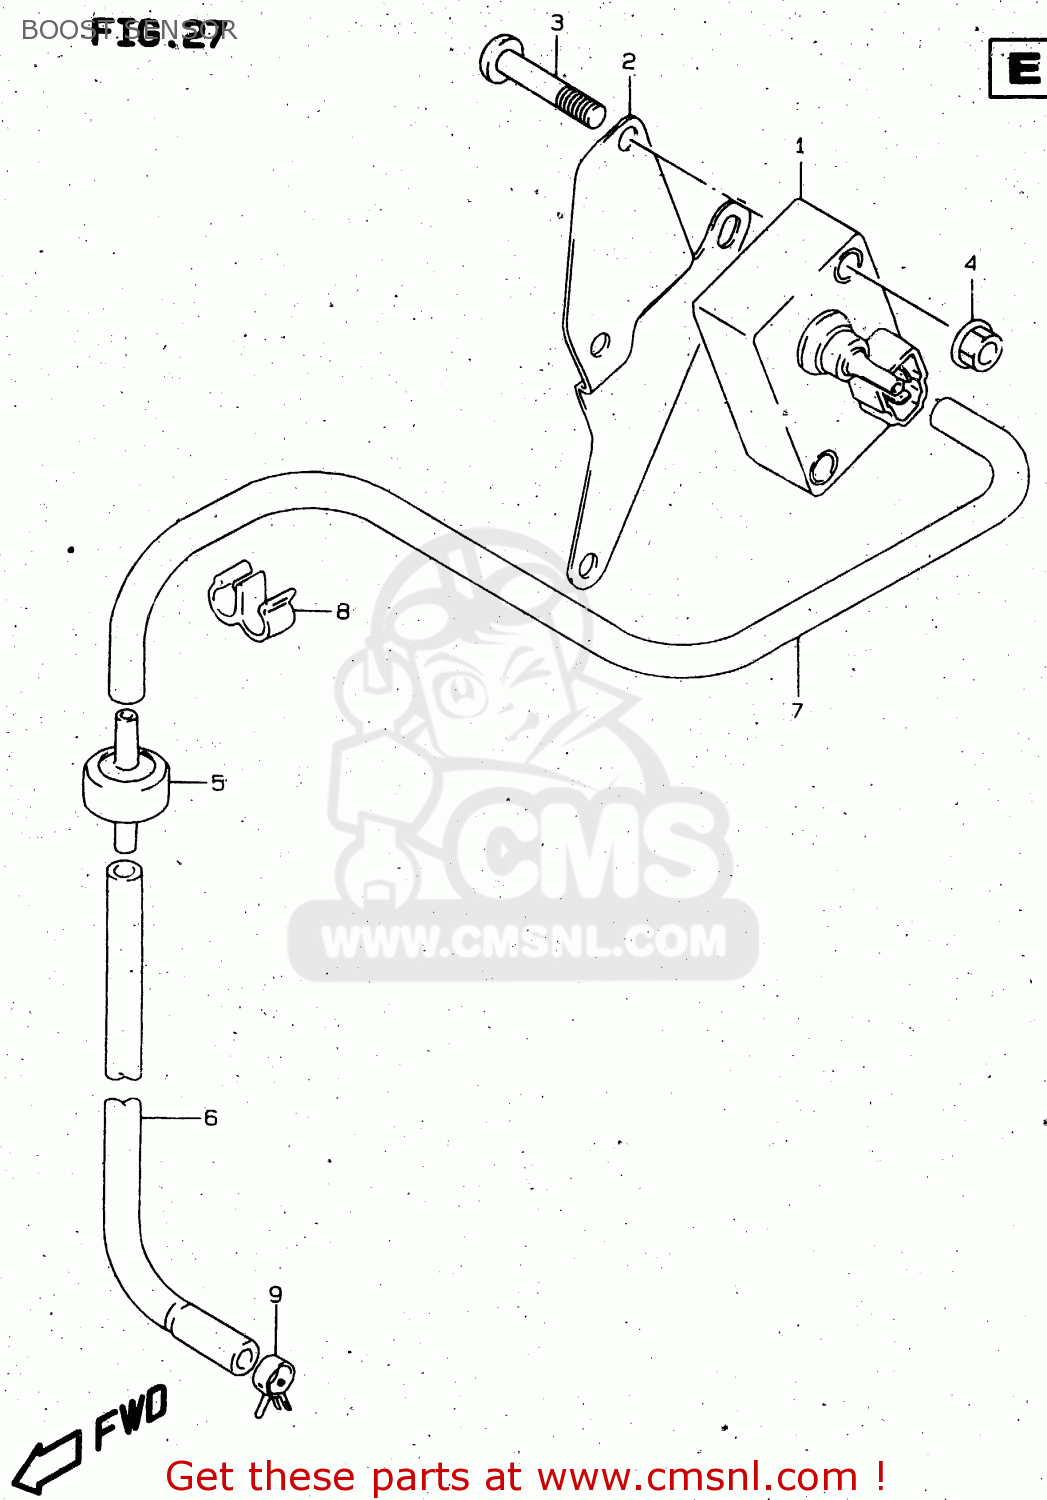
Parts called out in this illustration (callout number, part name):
1	SENSOR ASSY,BOOST
2	BRACKET,BOOST SENSOR
3	SCREW 6X30
4	NUT
5	FILTER,VSV
6	HOSE,BOOST NO.1
7	HOSE(3.5X7.5X2000)
8	CLAMP
9	CLIP
